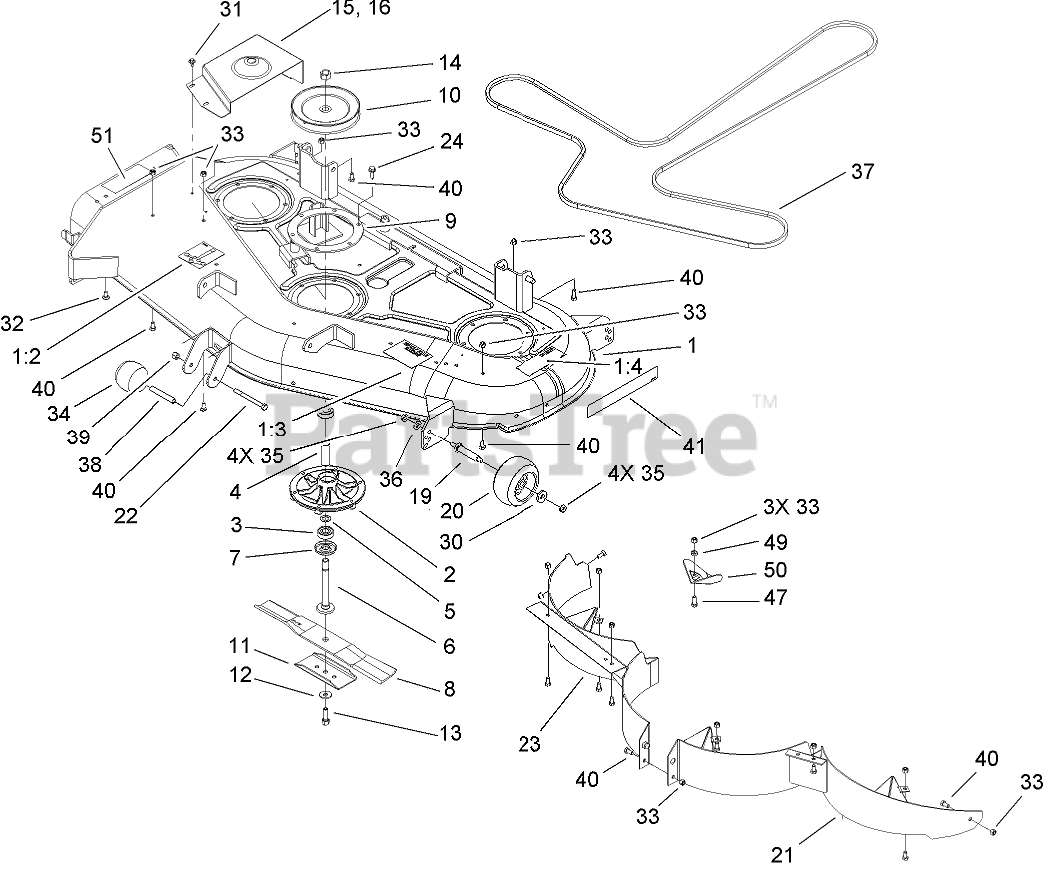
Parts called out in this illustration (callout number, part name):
1	Deck ASM
1:2	DECAL-ROUTING, BELT
1:3	DECAL-ANTI SCALP
1:4	DECAL-DANGER
2	HOUSING-SPINDLE
3	BEARING-BALL
4	SPACER
5	SPACER
6	SHAFT-SPINDLE
7	SHIELD-BEARING
8	BLADE-RECYCLER
9	RING-SUPPORT, DECK
10	PULLEY AND HUB ASM
11	STIFFENER-BLADE
12	WASHER-BELLEVILLE
13	SCREW-HH
14	NUT-HEX
15	COVER-BELT, LH
16	COVER-BELT, RH
19	SPACER
20	WHEEL-GAGE
21	LEFT BAFFLE ASM
22	SCREW-HH
23	RIGHT BAFFLE ASM
24	SCREW-TAPTITE
30	WASHER
31	SCREW-HHFTF
32	SCREW-CARR
33	NUT-LOCK, NI
34	ROLLER
35	NUT-HHF, WHIZ
36	WASHER-BELLEVILLE
37	BELT-V
38	TUBE-SPACER, WHEEL
39	NUT-LOCK, NI
40	SCREW-HH
41	Decal-Deck
47	SCREW-HH
49	SPACER
50	PLATE-KICKER
51	DECAL-DANGER, RIDER
